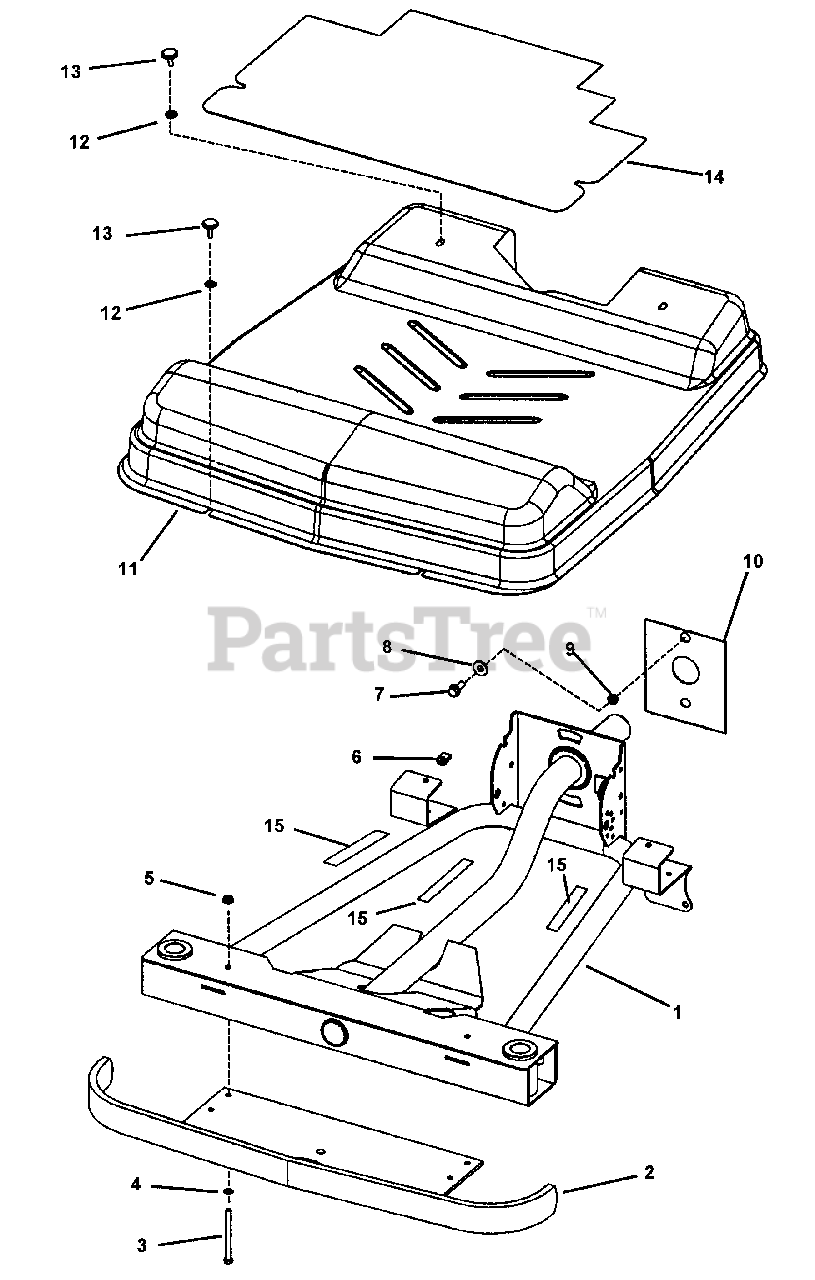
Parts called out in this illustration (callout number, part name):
1	FRAME, Front
2	BUMPER, Front
3	BOLT, 5/16-18 x 3-3/4"
4	WASHER, 5/16" Split Lock
5	NUT, 5/16-18 Hex Flange Lock, Grade 5
6	FASTENER, "U" Type 1/4"-20
7	SCREW, 3/8-16 x 1" Hex Self-Tapping
8	WASHER, 3/8" Flat
9	SPACER, Front Frame Pivot
10	PLATE, Front Frame Pivot
11	FLOOR, Front Frame
12	WASHER, 1/4" Internal/External Lock
14	FLOOR MAT
15	PAD, Floor Pan
